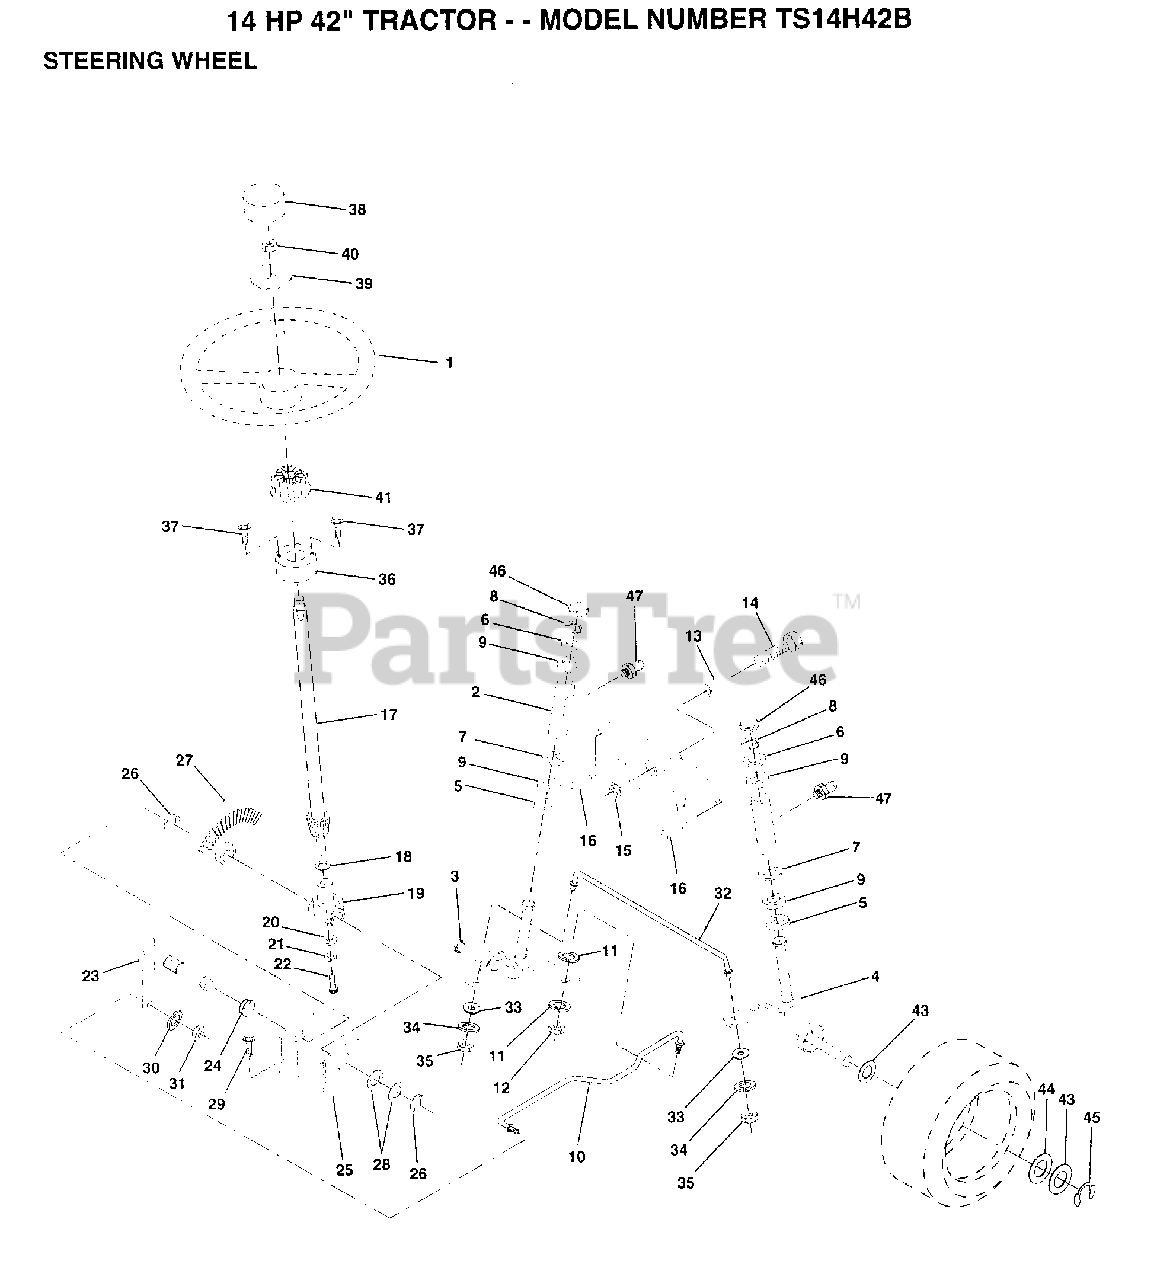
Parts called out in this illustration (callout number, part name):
2	AXLE ASM FRONT
3	SPINDLE LH
4	SPINDLE RH
5	WASHER .T
6	WASHER
7	WASHER
8	RING
9	COL. SRTG. BEAR.
11	LOCKWASHER
13	BEARING
14	BOLT HEX 5/8-11
15	"NUT-LOC,FLANGE LT"
16	AXLE PIN
17	STEERING SHAFT
18	THRUST WASHER
19	SUPPORT.SHAFT
21	LOCKWASHER
22	"SCREW,SPECIAL"
24	NYLINER T
25	"BRKT,STEERING"
26	RING
27	GEAR SECTOR
28	WASHER .T
29	SCREW
30	LOCKWASHER
32	TIE ROD
33	WASHER M
34	LOCKWASHER
35	NUT.LOCK.5/16-24
38	"INSERT,STR WHEEL"
39	WASHER
41	ADAPTER LT
43	WASHER
44	WASHER
45	RING
46	CAP
47	ZERK M
